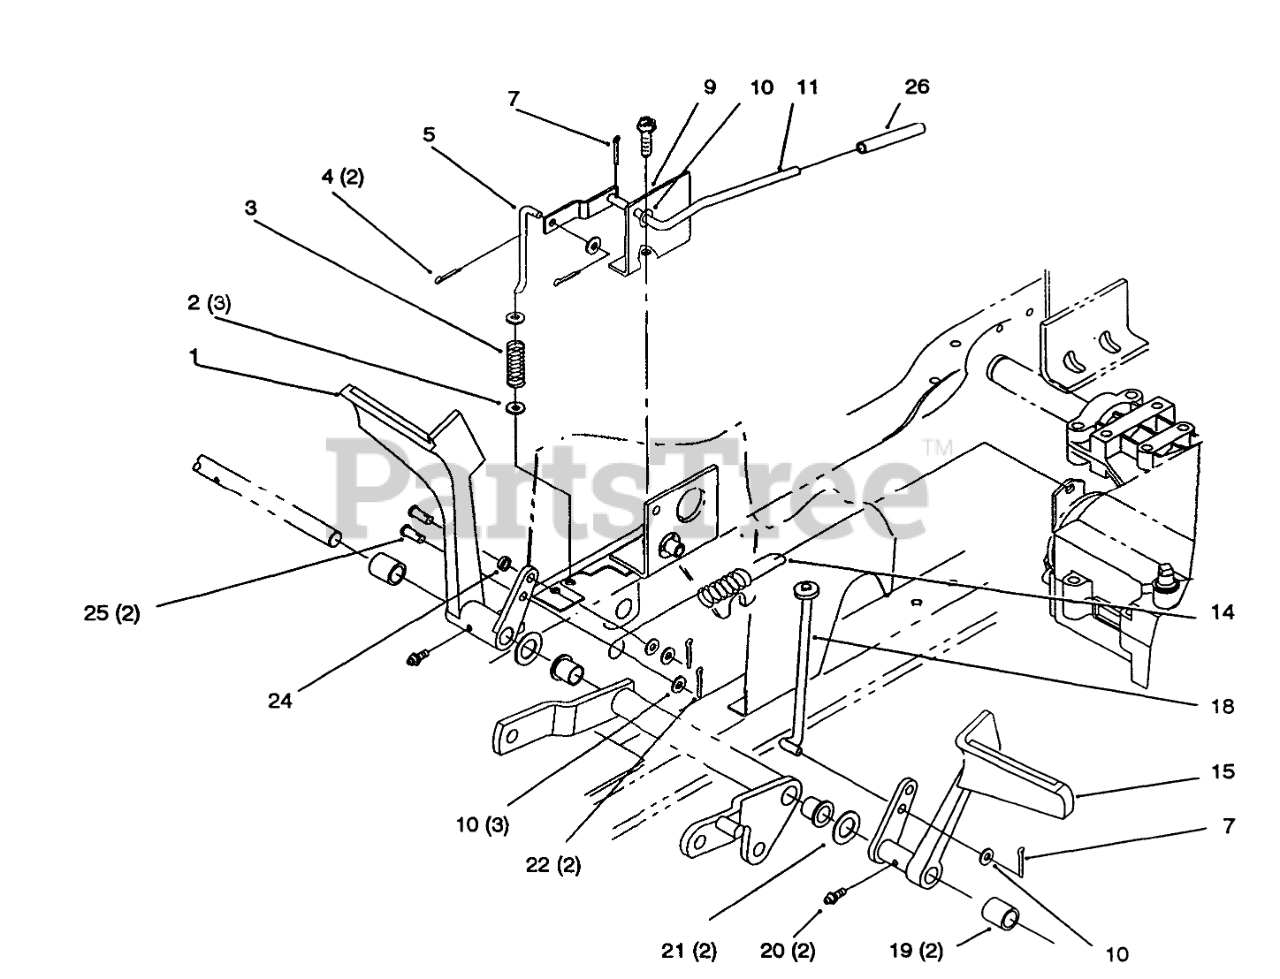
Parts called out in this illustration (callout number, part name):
1	Pedal-Brake (Only On: 72042, 72062)
2	Washer-Flat (Only On: 72042, 72062)
3	Spring-Compression (Only On: 72042, 72062)
4	Pin-Cotter (Only On: 72042, 72062)
5	Rod-Park Brake (Only On: 72042, 72062)
7	Pin-Cotter (Only On: 72042, 72062)
9	Bracket-Parking Brake (Only On: 72042, 72062)
10	Washer-Flat (Only On: 72042, 72062)
11	Lever-Parking Brake (Only On: 72042, 72062)
14	Spring-Extension (Only On: 72042, 72062)
15	Pedal-Clutch (Only On: 72042, 72062)
18	Rod-Clutch (Only On: 72042, 72062)
19	Spacer (Only On: 72042, 72062)
20	Fitting-Grease (Only On: 72042, 72062)
21	Washer-Wave (Only On: 72042, 72062)
22	Pin-Cotter (Only On: 72042, 72062)
24	Spacer (Only On: 72042, 72062)
25	Pin-Clevis (Only On: 72042, 72062)
26	Grip-Parking Brake (Only On: 72042, 72062)
